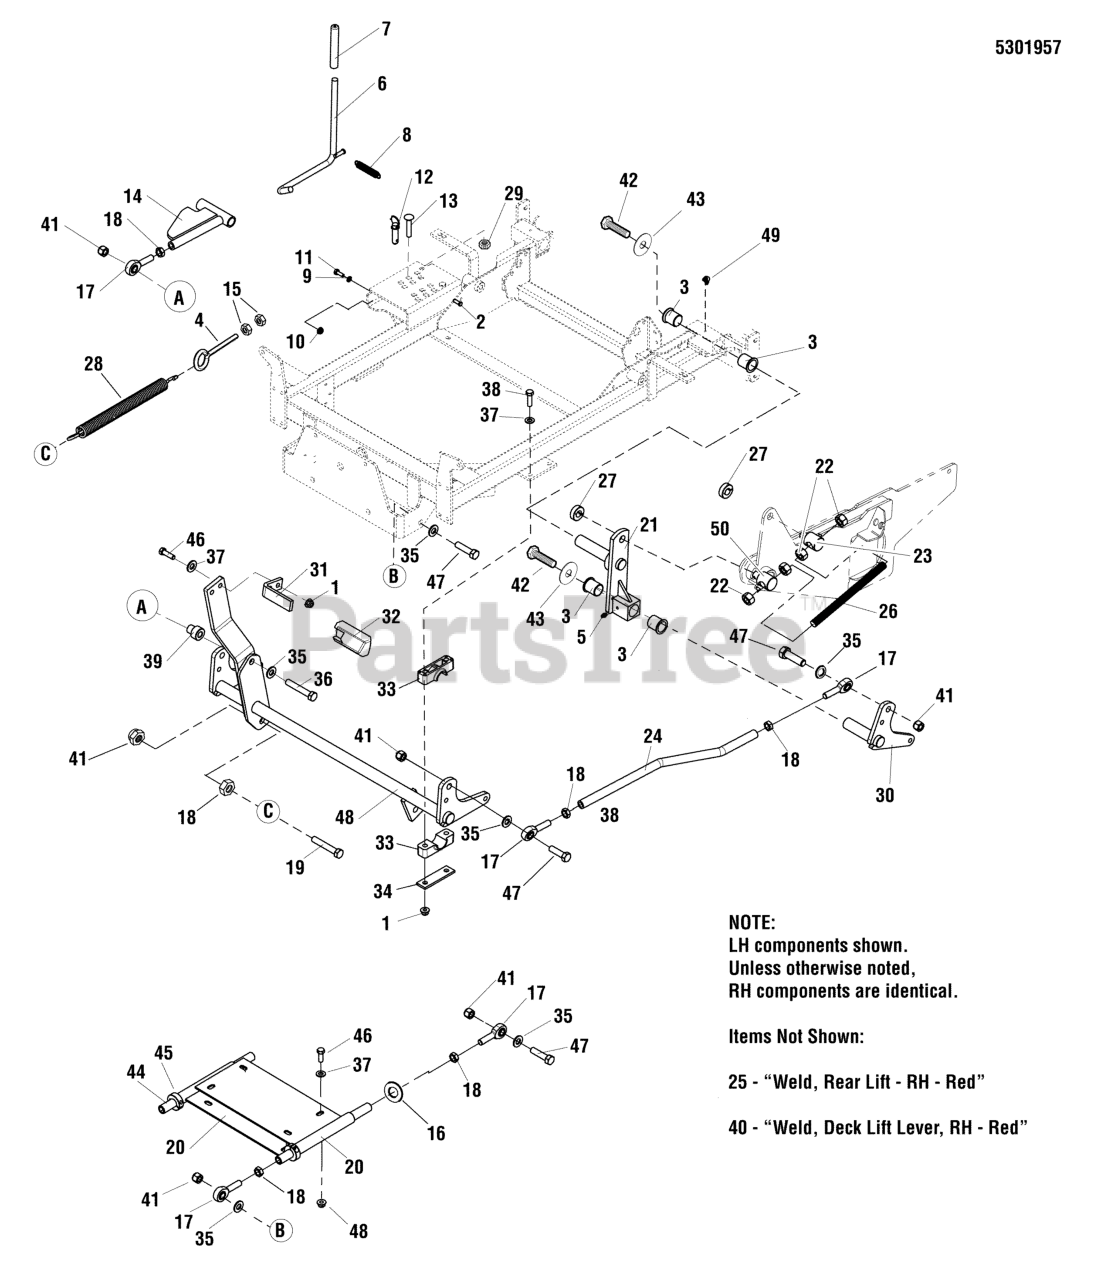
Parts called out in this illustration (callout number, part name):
1	NUT, 3/8-16 HEX NYLOCK FLANGE
2	CLEVIS PIN, 1/4 X 1/2, YZ
3	BUSHING, 1.00 X 1.13 X 1.38, PLASTIC
4	EYE BOLT, 3/8-16 X 6.88, 3THRD, 1EYE
5	GREASE FITTING, 1/4-28 STRAIGHT
6	WELD, ROD DECK LIFT - BLK
7	GRIP, FOAM
8	SPRING, EXTENSION
9	WASHER, 1/4 SAE
10	NUT, 1/4-20 HEX SERR. FLANGE
11	BOLT, 1/4-20 X 3/4 GD5 YZ
12	PIN, HITCH, 1/2 X 2.00 OAL, YP
13	BOLT, 3/8-16 X 2, CARRIAGE
14	WELD, DECK ADJUST LINK - RED
15	NUT, 3/8-16 HEX
16	WASHER, 1/2 SAE
17	BALL JOINT, 1/2-20, MALE
18	NUT, 1/2-20 HEX JAM
19	BOLT, 1/2-13 X 2-1/4" GD5 CZ
20	WELD, DECK STABILIZER - BLK
21	WELD, REAR LIFT, LH - BLK
22	NUT, 5/8-11 HEX
23	PIVOT, SPRING ROD
24	ROD, DECK LIFT BENT
25	WELD, REAR LIFT, RH - BLK
26	ROD, 5/8-11 X 9.00
27	COLLAR, 5/8 SPLIT
28	SPRING, DECK LIFT ASSIST
29	NUT, 3/8-16 HEX SIDE LOCK
30	WELD, DECK LIFT LEVER, LH - BLK
31	PEDAL, FOOT - BLK
32	PEDAL, Rubber
33	PIVOT BLOCK, PLASTIC
34	PLATE, PIVOT BLOCK SUPPORT - BLK
35	WASHER, 1/2 GD9 YZ
36	BOLT, 1/2-13 X 3-1/2, HEX HD, GD5, CZ (SV)
37	WASHER, 3/8 SAE
38	BOLT, 3/8-16 X 2-3/4" GD5 CZ
39	ADAPTER, CASTER AXLE, CZ
40	WELD, DECK LIFT LEVER, RH - BLK
41	NUT, Hex, Nylon Lock, 1/2-20
42	BOLT, 3/8-16 X 3/4, PLT W/PATCH
43	WASHER, .390 X 1.50 X .109, YZ
44	SHAFT, DECK STABILIZER
45	COLLAR, 3/4 SPLIT
46	BOLT, 3/8-16 X 1" GD5 CZ
47	BOLT, 1/2-20 X 1-3/4" GD8 CZ
48	WELD, DECK LIFT SHAFT - RED
49	GREASE FITTING, 1/4-28, 90 DEGREE
50	PIVOT, SPRING ROD
